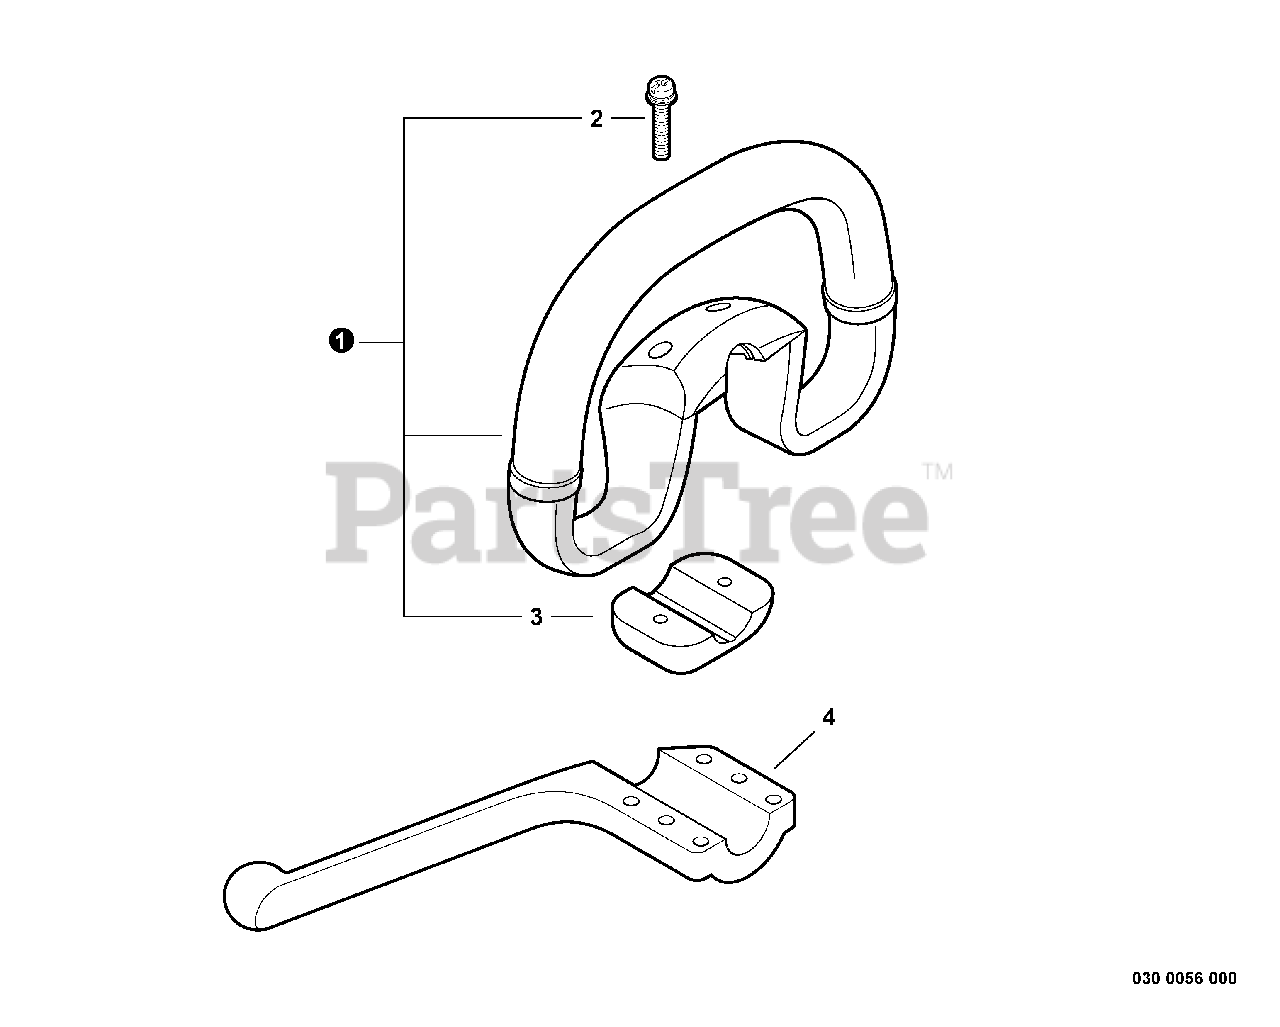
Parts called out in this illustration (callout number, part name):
1	HANDLE KIT - FRONT
2	SCREW - 5X40
3	BRACKET, HANDLE
4	BAR, BARRIER
